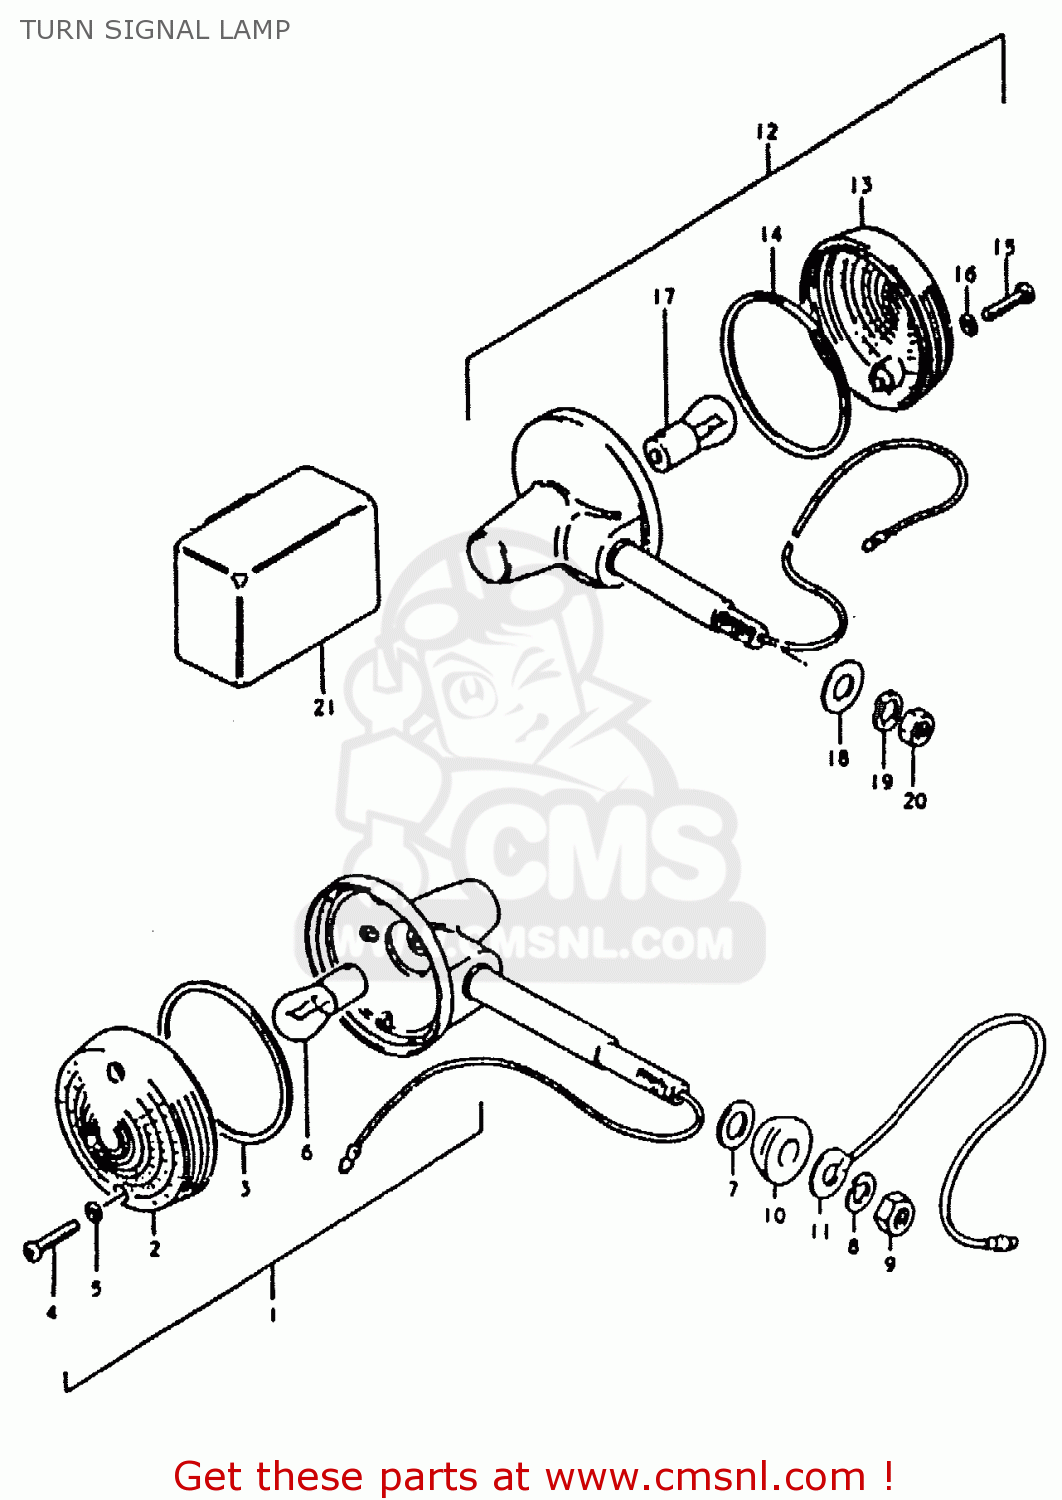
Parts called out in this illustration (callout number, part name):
1	LAMP ASSY, FRONT TURN SIGNAL
2	LENS
3	GASKET (NAS)
4	SCREW
5	GASKET (NAS)
6	BULB (6V,18W)
7	WASHER
8	LOCK WASHER
9	NUT
10	SPACER,TURN SIGNAL LAMP
11	WIRE
12	LAMP, REAR TURN SIGNAL
13	LENS
14	GASKET (NAS)
15	SCREW
16	GASKET (NAS)
17	BULB (6V,18W)
18	WASHER
19	LOCK WASHER
20	NUT
21	RELAY,TURN SIGNAL
